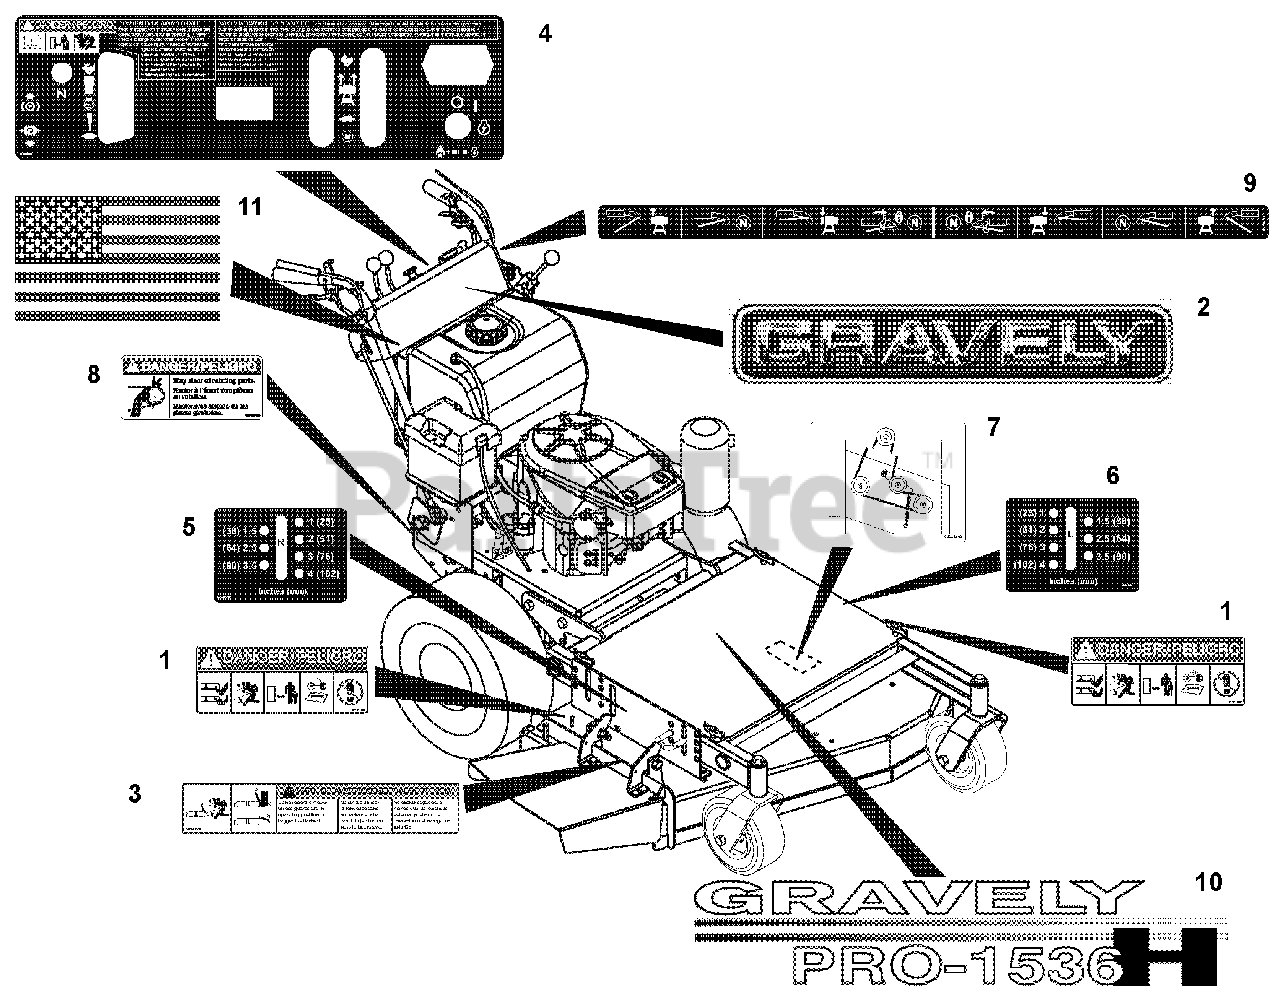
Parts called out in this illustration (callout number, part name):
1	Decal, Mower Pan Head Danger
2	Decal- 15" Gravely Logo
3	Decal, Warning (106, 120)
4	Decal, Control HR15 (105, 106)
5	Decal, Height of Cut-Fixed- Right Hand
6	Decal, Height of Cut-Fixed- Left Hand
7	Decal, Belt Diagram-2 Spindle (105, 120)
8	Decal, Danger-Belt Rotating
9	Decal, Steer Levers (Hydro)
10	Decal, Pro 1536H (120, 105)
11	Decal, American Flag
